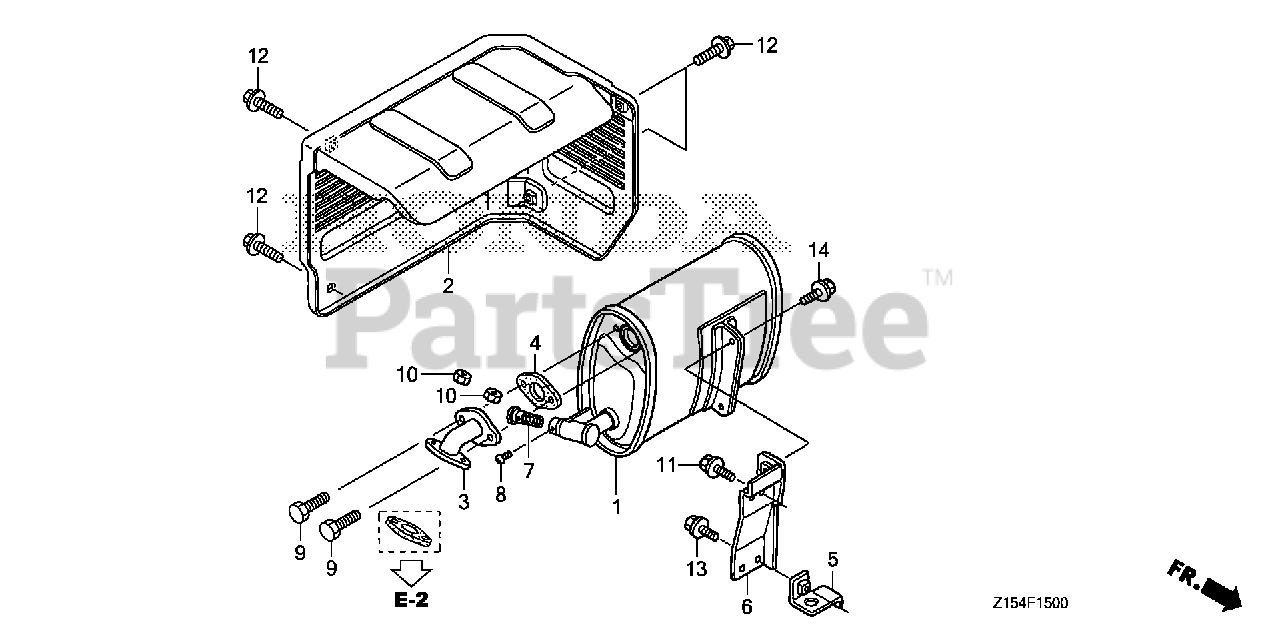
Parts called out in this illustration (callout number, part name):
1	MUFFLER
2	PROTECTOR, MUFFLER *NH105* (MAT BLACK)
4	GASKET, EX. PIPE
5	STAY A, MUFFLER
6	STAY B, MUFFLER
7	ARRESTER, SPARK
8	SCREW, TAPPING (4X6)
9	BOLT, HEX. (8X25)
10	NUT, HEX. (8MM)
11	BOLT, FLANGE (6X12)
12	BOLT, FLANGE (6X12)
13	BOLT, FLANGE (8X14)
14	BOLT, FLANGE (8X16)
